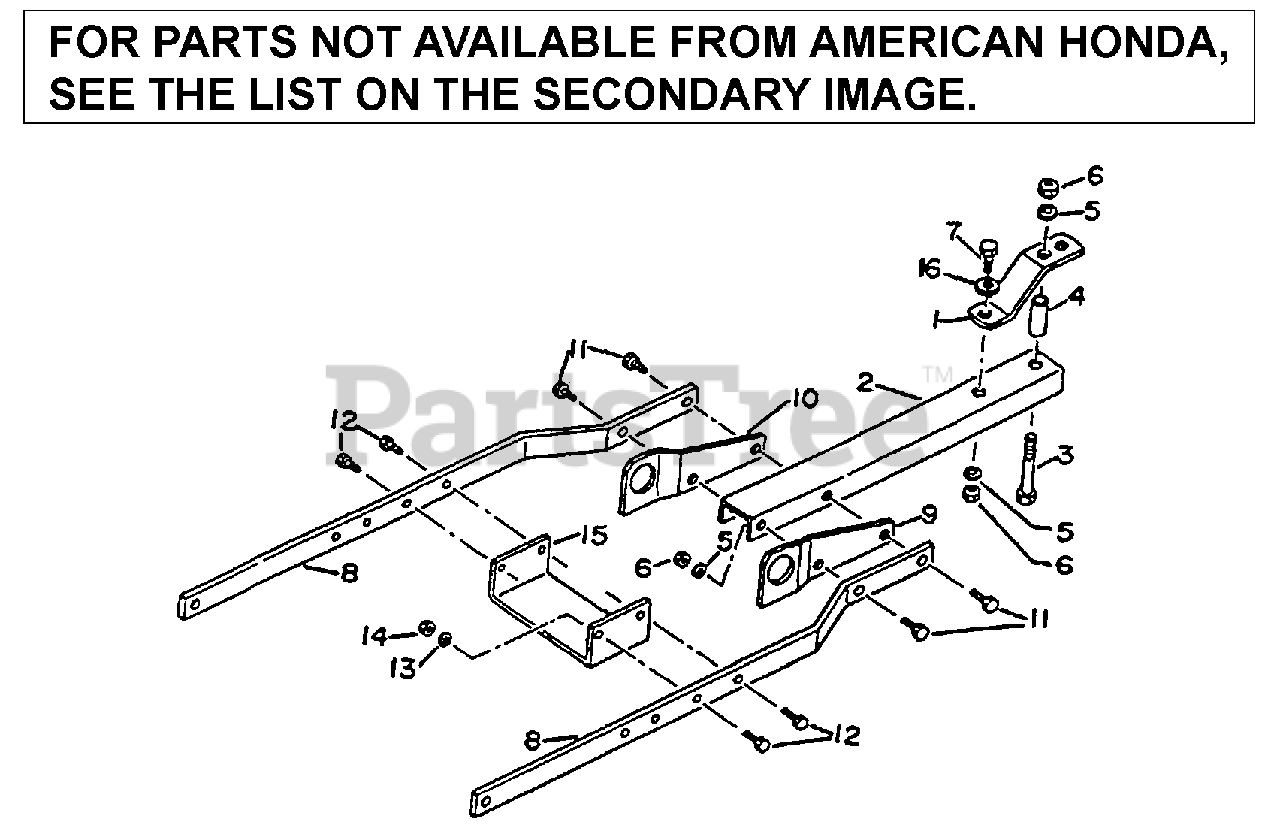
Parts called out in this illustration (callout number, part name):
1	PLATE, HITCH
2	CHANNEL, SUB-FRAME
4	SPACER, TUBE
8	FLATBAR, SUB-FRAME
9	BRACKET, L. LIFT SUPPORT
10	BRACKET, R. LIFT SUPPORT
15	PLATE, SUPPORT
